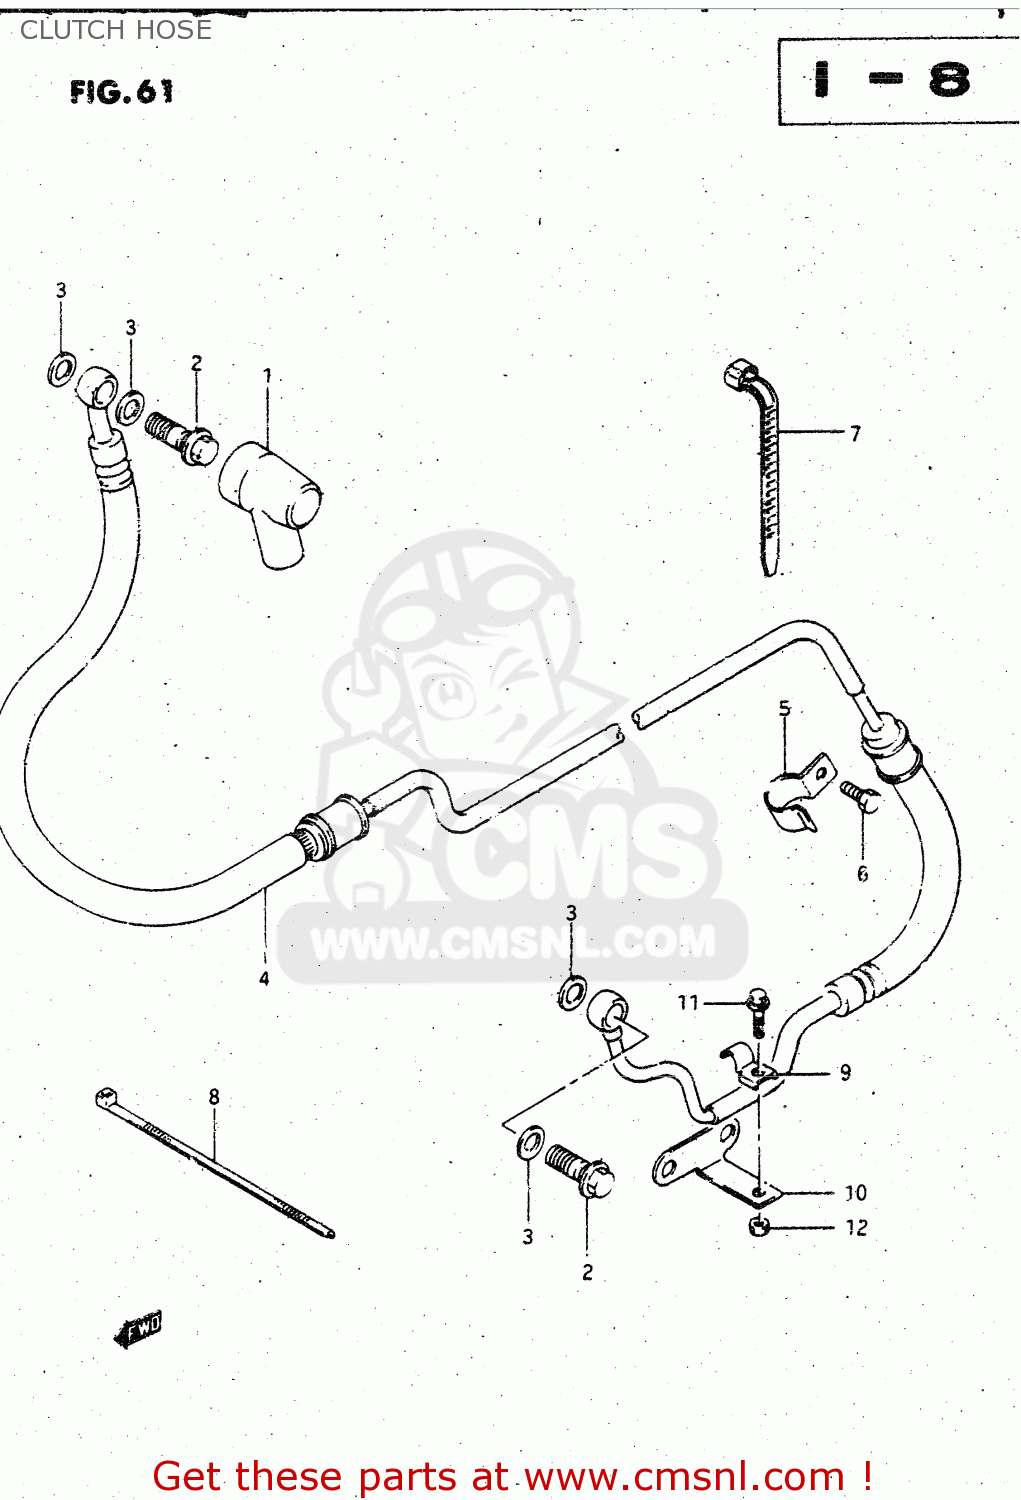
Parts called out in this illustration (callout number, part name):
1	BOOT,MASTER CYLINDER
2	BOLT UNION
3	WASHER(10X15X1.5)
4	HOSE,CLUTCH
5	GUIDE
6	BOLT
7	CLAMP(L:165)
8	CLAMP(L:250)
9	CLAMP, CLUTCH HOSE/GEAR CASE
10	CLAMP,CLUTCH HOSE
11	BOLT 6X12
12	NUT
